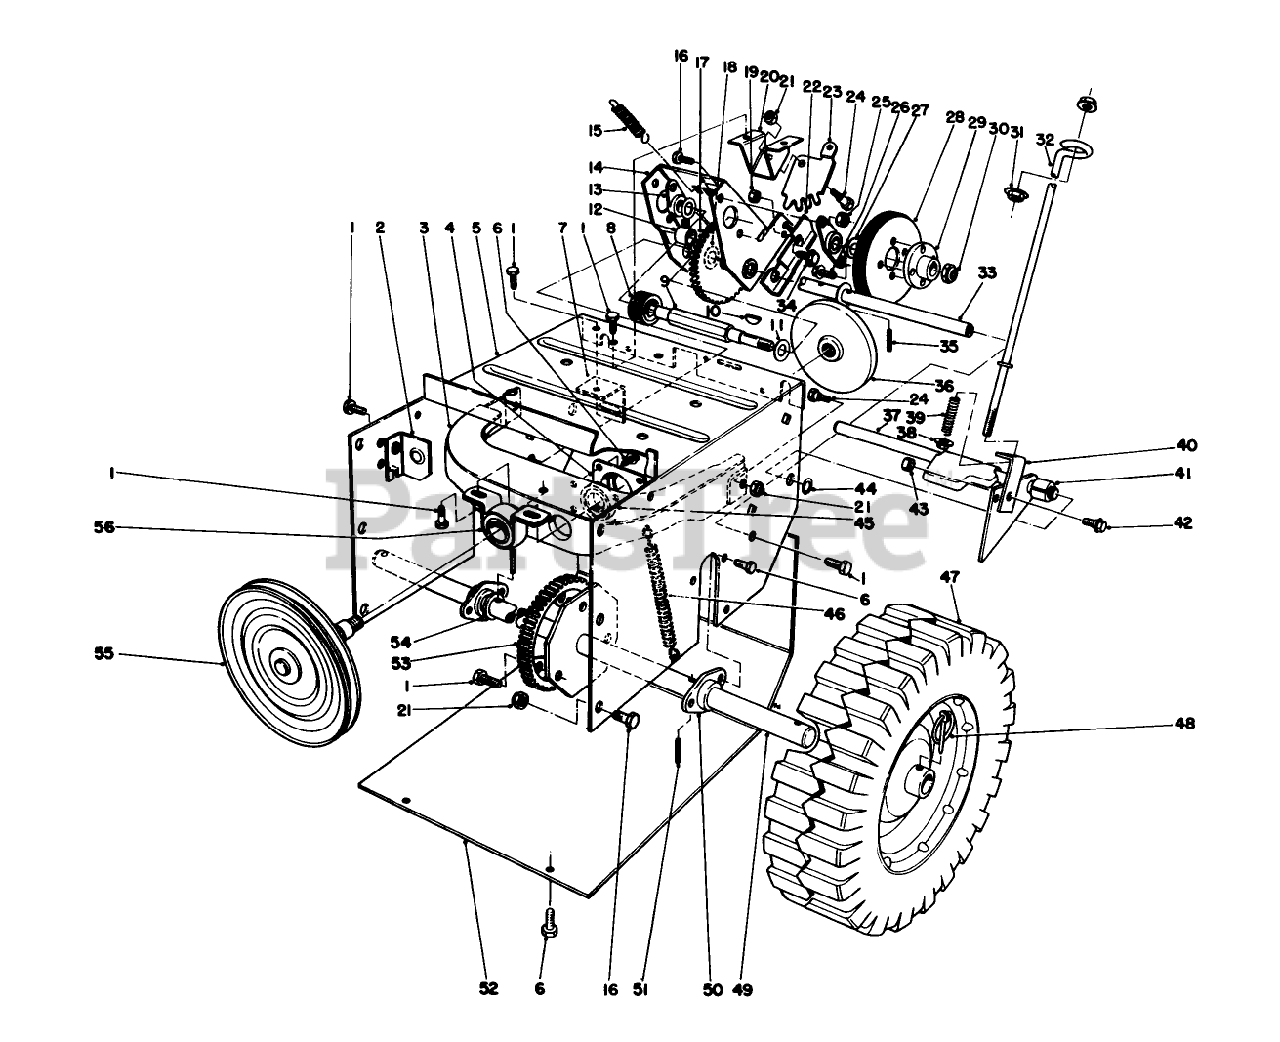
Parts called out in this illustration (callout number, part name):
1	SCREW-THD ROLL, HWH
3	FRICTION PLT FRAME
4	CUP-BEARING
6	SCREW-HWH
7	BRACKET-MOUNT, REAR
8	PINION
9	SHAFT-WHEEL, FRICTION
10	KEY-WOODRUFF
11	WASHER-FLAT
12	5/8ID X 1LG BUSHING
13	BEARING-WHEEL, FRICTION
14	BRACKET-SLIDING
15	SPRING-TRACTION
16	SCREW-HH
17	INTERNAL GEAR AND BUSHING ASM
18	WASHER-SPECIAL
19	NUT-LOCK, NI
20	MOUNT-LEVER
21	NUT-LOCK, NI
22	CAM-RECEIVER
23	GEAR-QUADRANT
24	BOLT-SHOULDER
25	NUT-LOCK, CONE
26	SCREW-HWHTF
27	Washer
28	WHEEL-FRICTION
29	HUB-WHEEL, FRICTION
30	NUT-LOCK, NI
31	NUT-HF
32	ROD-TRACTION, LOWER
33	SHAFT-PIVOT
35	PIN-SPRING
36	PLATE-FRICTION
38	NUT-HHF
39	SPRING
40	BRACKET-TRACTION
41	SPACER
42	SCREW
43	NUT-LOCK, NI
44	RING-RETAINING
45	BEARING-BALL
46	SPRING-PLATE, FRICTION
48	PIN-LYNCH
49	AXLE SHAFT WA
50	BEARING-AXLE
51	PIN-SPRING
53	GEAR-AXLE
54	WASHER-THRUST
